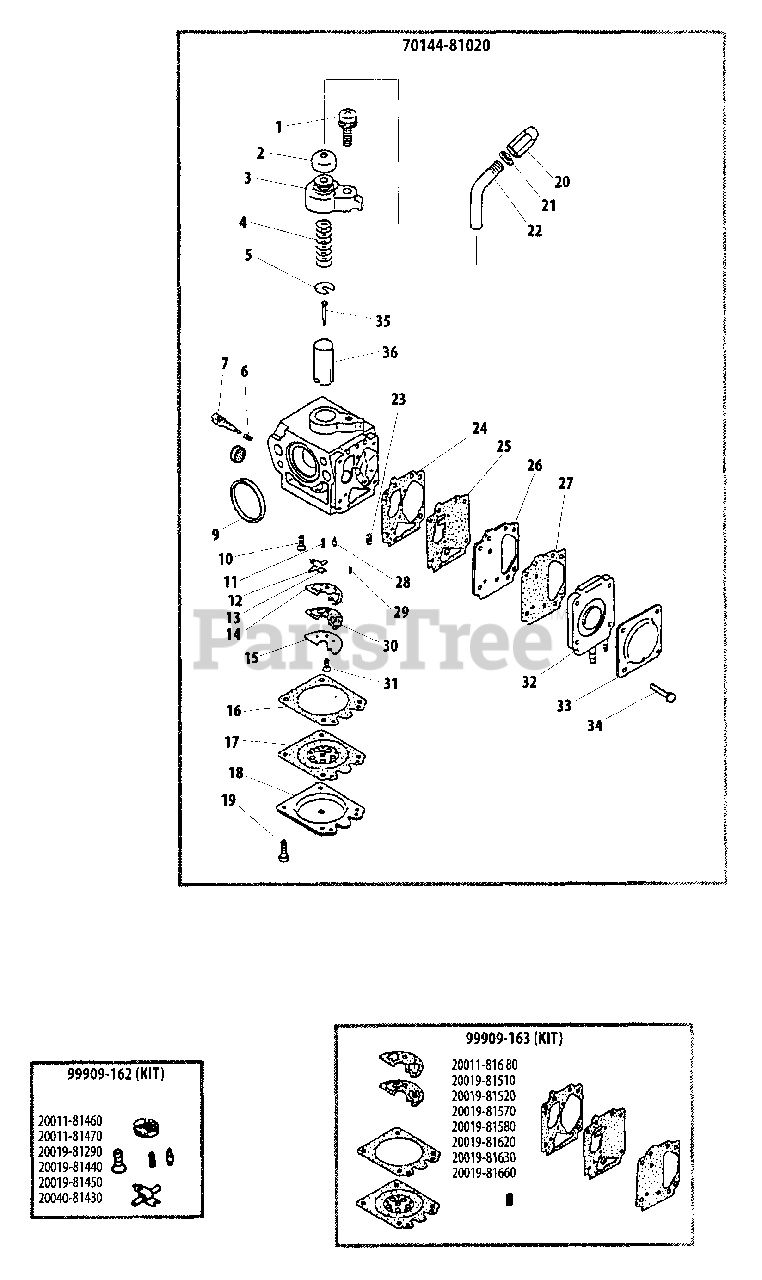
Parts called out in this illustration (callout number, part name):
1	SCREW - 5X15
2	GROMMET
3	CAP, CARBURETOR
4	SPRING, THROTTLE
5	RETAINER
6	SCREW, IDLE ADJUST
7	SCREW, IDLE ADJUST
9	SEAL
10	SCREW, METERING LEVER PIN
11	SPRING
12	PIN, METERING LEVER
13	LEVER, METERING
14	GASKET
15	PLATE
16	GASKET, METERING
17	DIAPHRAGM, METERING
18	COVER, DIAPHRAGM
19	SCREW
20	NUT, CABLE ADJUST
21	LOCKNUT
22	GUIDE, CABLE
23	STRAINER
24	GASKET, PUMP
25	DIAPHRAGM, PUMP
26	PLATE, PUMP
27	GASKET, PUMP
28	VALVE, INLET NEEDLE
29	SPRING
30	VALVE, CHECK
31	SCREW, METERING LEVER PIN
32	COVER, PUMP
33	COVER, DIAPHRAGM
34	SCREW - 3X14
35	NEEDLE, JET
36	VALVE, THROTTLE
A	CARBURETOR
A	REPAIR KIT
A	DIAPHRAGM/GASKET KIT
